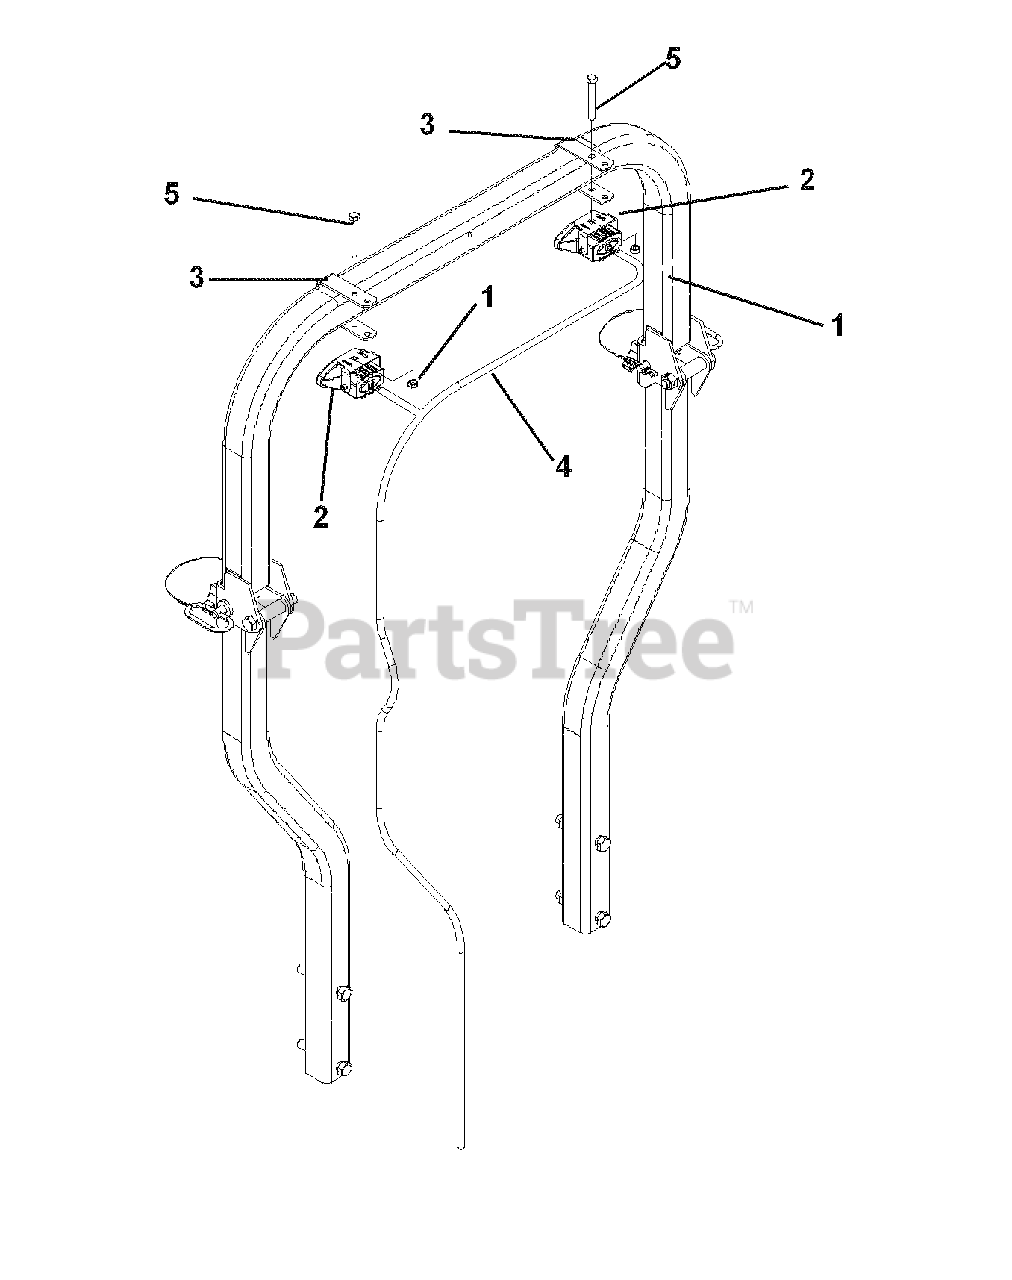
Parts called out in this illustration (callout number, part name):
1	NUT, 5/16-18, JAM
2	LIGHT W/BRKT & HRDWARE
3	LIGHT MOUNTING BRACKET
4	LIGHT HARNESS
5	HCS, 5/16-18 x 2 1/2
